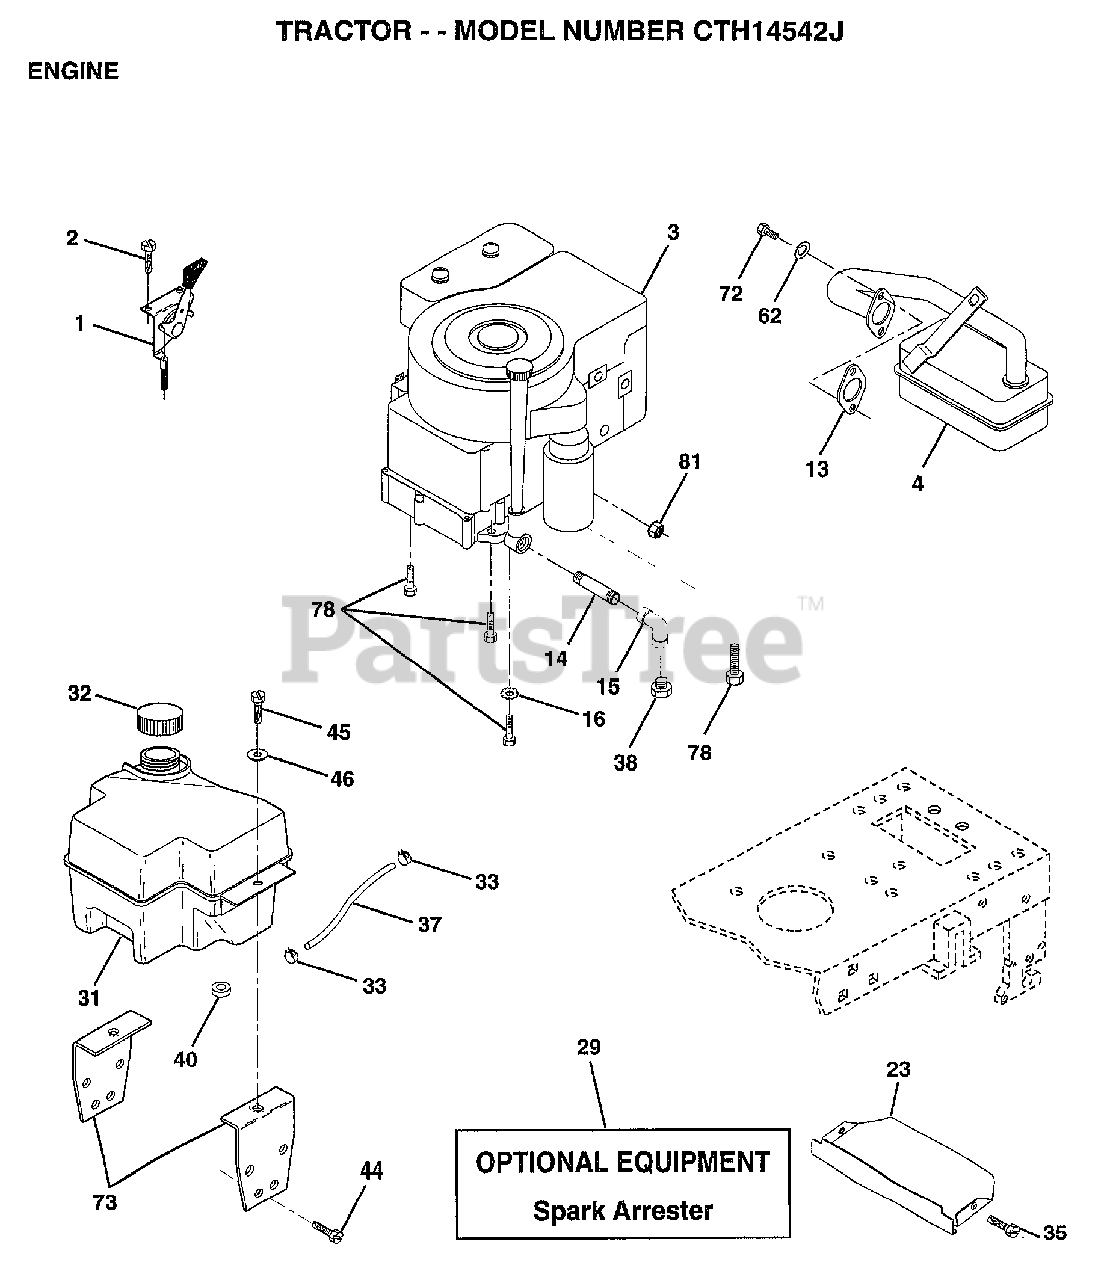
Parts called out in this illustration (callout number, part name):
1	CONTROL.THTL.19.6
2	SCREW LT
4	MUFFLER
14	PIPE NIPPLE
15	ELBOW
16	LOCKWASHER
23	SHIELD.BRN/DBR.GD
31	TANK.FUEL.FRONT.
32	CAP ASM FUEL
33	HOSE CLAMP
35	SCREW
37	LINE FUEL
44	SCREW
45	SCREW HEX CRT
46	WASHER
62	LOCKWASHER
72	SCREW
73	BRACKET.SUPT.TANK
78	SCREW
81	NUT
